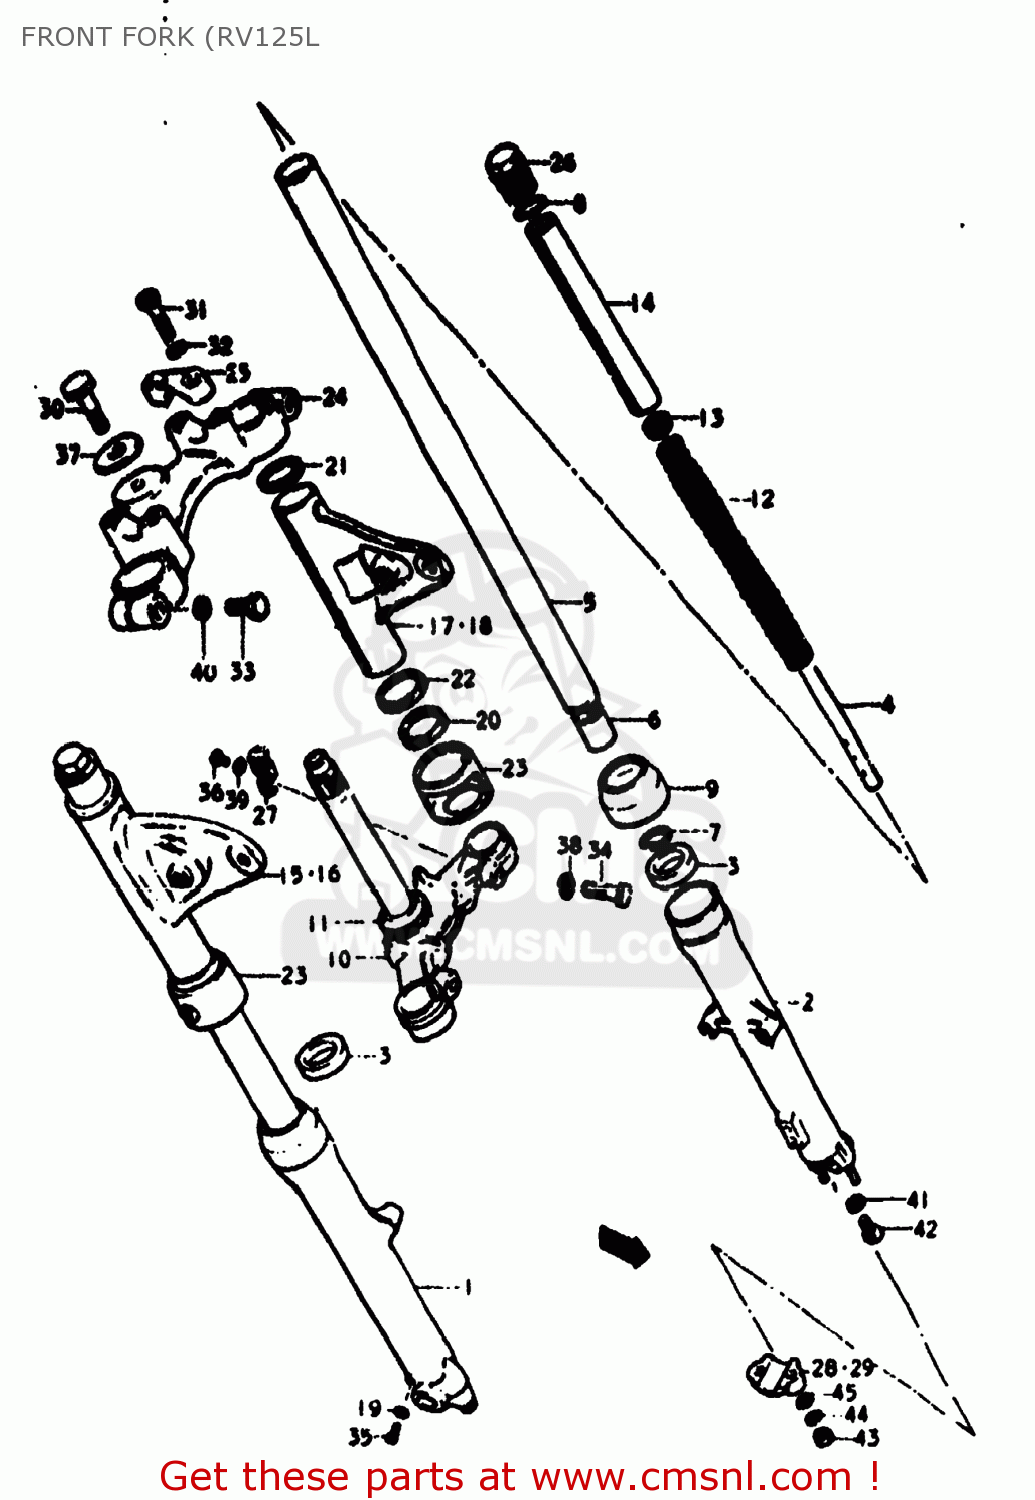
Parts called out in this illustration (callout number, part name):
0	DAMPER SET
1	TUBE,OUTER,RIGHT
2	TUBE,OUTER,LEFT
3	SEAL,OIL
4	CYLINDER,FRONT FORK
5	TUBE,INNER
6	PISTON
7	SNAP RING
8	O-RING,FORK INNER TUBE
9	SEAL,DUST
10	STEM,STEERING
11	RACE,STEERING OUTER LWR
12	SPRING,FRONT FORK
13	GUIDE,SPRING
14	SPACER,SPRING
15	BRACKET,HEADLAMP HOUSING
16	BRACKET,HEADLAMP HOUSING
17	BRACKET,HEADLAMP,LEFT
18	BRACKET,HEADLAMP,LEFT
19	GASKET,DRAIN,PLUG (NAS)
20	CUSHION,HEADLAMP BRACKET
21	SEAT,HEADLAMP BRACKET
22	SEAT,HEADLAMP BRACKET
23	CUSHION,HEADLAMP BRACKET
24	HEAD,STEERING STEM
25	HOLDER,HANDLEBAR
26	BOLT,FR FORK
27	CLIP,BRAKE CABLE
28	HOLDER,AXLE
29	HOLDER,AXLE
30	BOLT,FORK INNER TUBE
31	Bolt
32	LOCK WASHER
33	BOLT,FORK INNER TUBE F
34	BOLT 10X40
35	SCREW
36	SCREW
37	WASHER
38	WASHER,LOCK 12
39	LOCK WASHER
40	LOCK WASHER
41	GASKET
42	BOLT
43	NUT (8MM)
44	LOCK WASHER
45	WASHER
